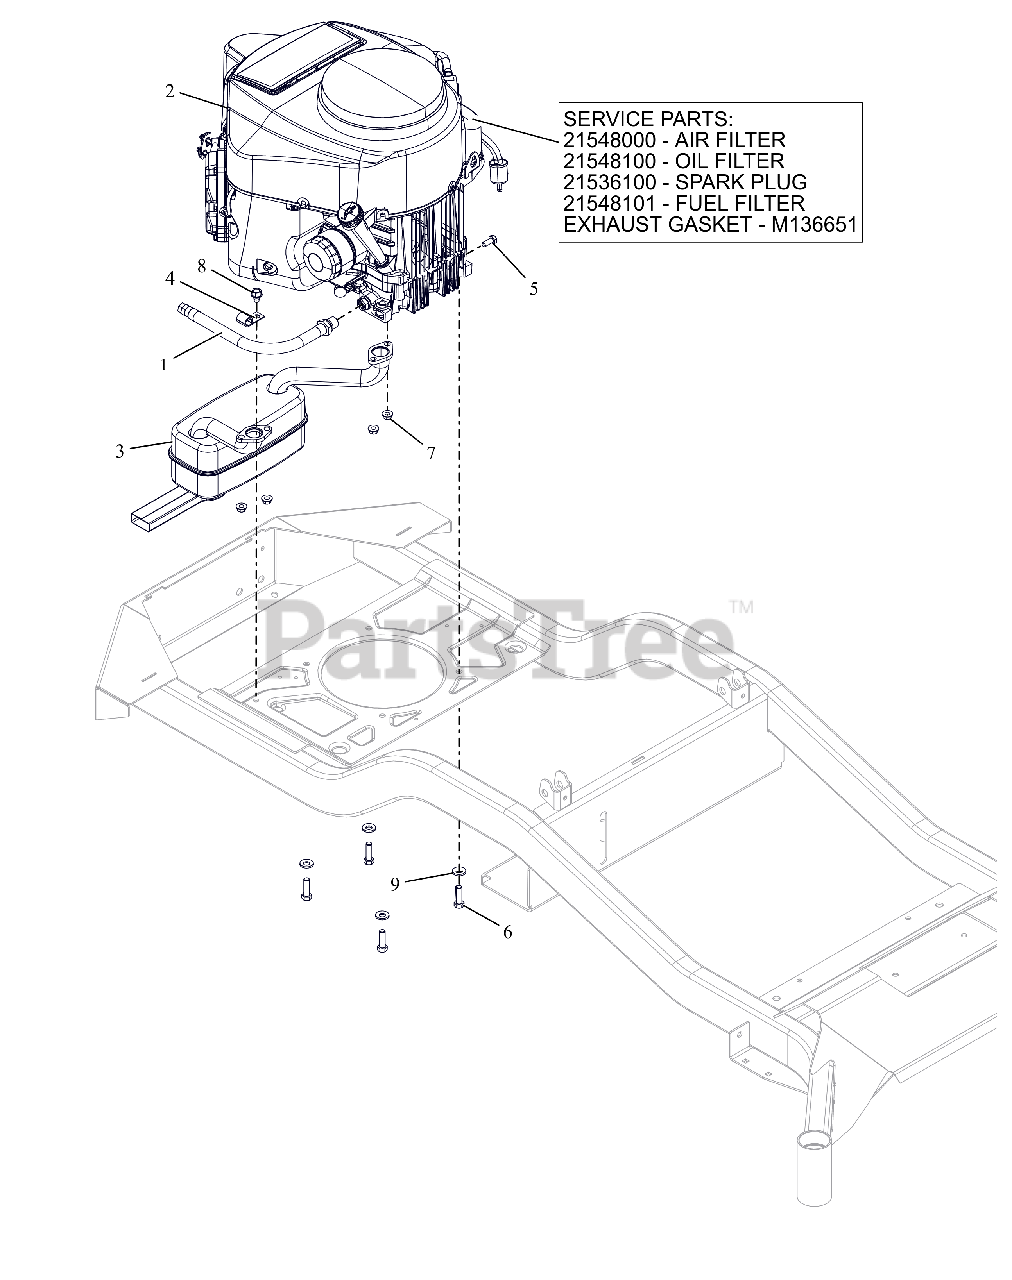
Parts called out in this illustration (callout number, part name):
1	HOSE, OIL DRAIN
2	ENGINE, KAWASAKI FR691 23HP
2	AIR FILTER, KAWASAKI FR
2	OIL FILTER, KAWASAKI FR
2	PLUG, SPARK
2	FUEL FILTER-KAWASAKI FR
2	GASKET, MUFFLER #
3	MUFFLER, KAWASAKI
4	J-CLAMP
5	BLT, HEX M8-1.25X20 G8.8 ZCC
6	BLT, HEX .38-16X1.25 G5 ZCC NT
7	NUT-LK-TOP-FLG M8 ZCC
8	SCR,TAP .375-16X.50 HWH TR ZCC
9	WASHER, 3/8" SPRING DISC
